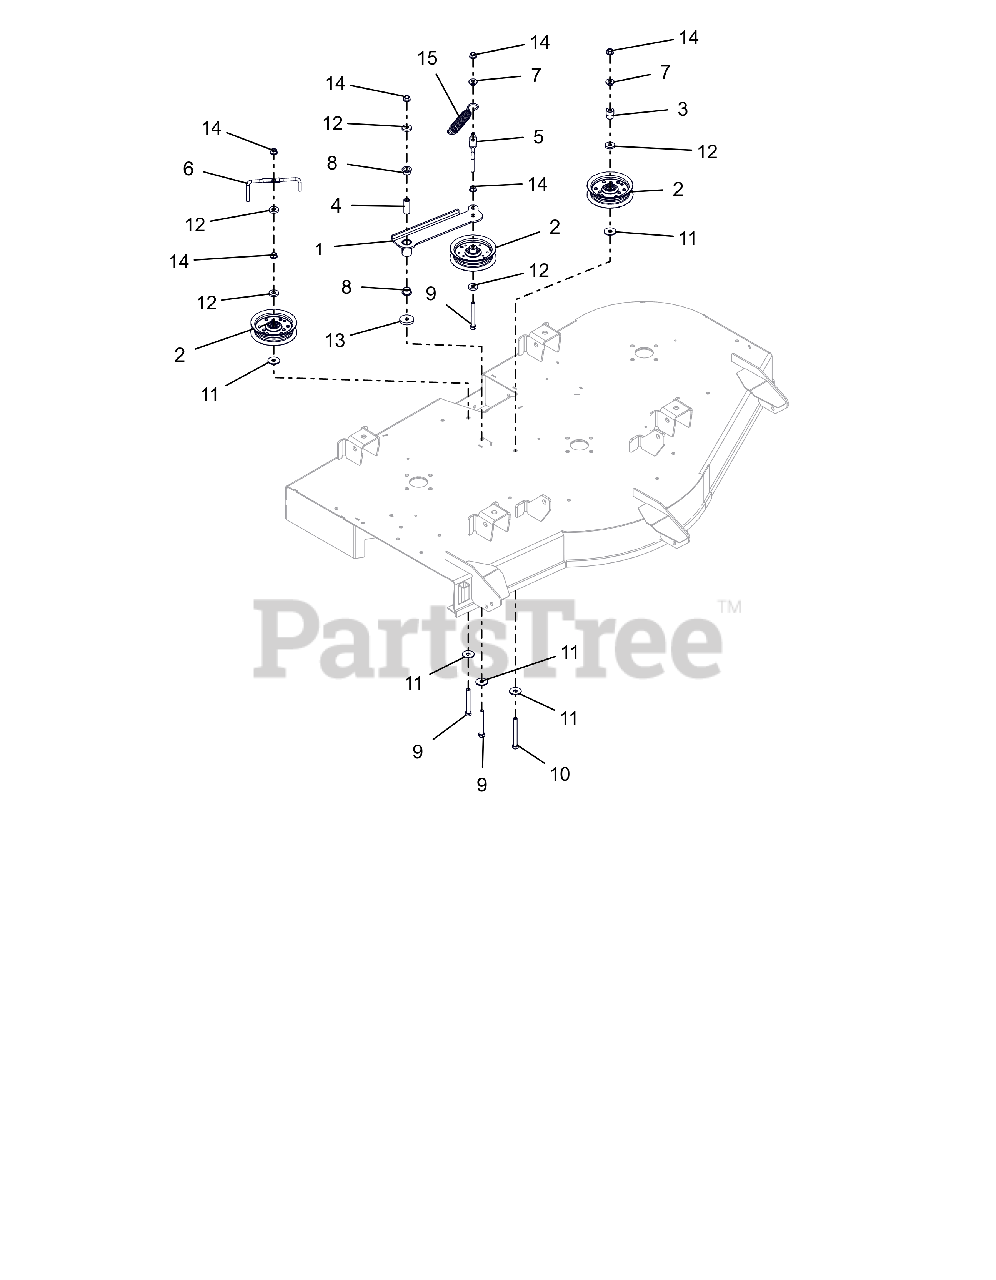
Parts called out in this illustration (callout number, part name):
1	WLDMT, IDLER ARM-52"
2	ASM, IDLER 4"
3	BUSHING, IDLER (P/M)
4	SPACER, .375IDX.625ODX1.66 PM
5	WIREFORM, BELT FINGER
6	WIREFORM, BELT FINGER
7	BSHG-FLG .385X.500X.875X.406
8	BSHG-FLG, .625X.750X.500X1.00
9	BLT, HEX .38-16X3.00F G5 ZCC
10	BLT, HEX .38-16X3.50 G5 ZCC
11	WSHR FL STL .406X1.25X.10ZC120
12	WSHR, FLT .406X1.00X.188 ZCC
13	WSHR, FLT .406X1.50X.245 ZCC
14	NUT-LK-TOP-FLG .38-16 ZC120
15	SG-TENS .135X.98X6.0 WLD 62
